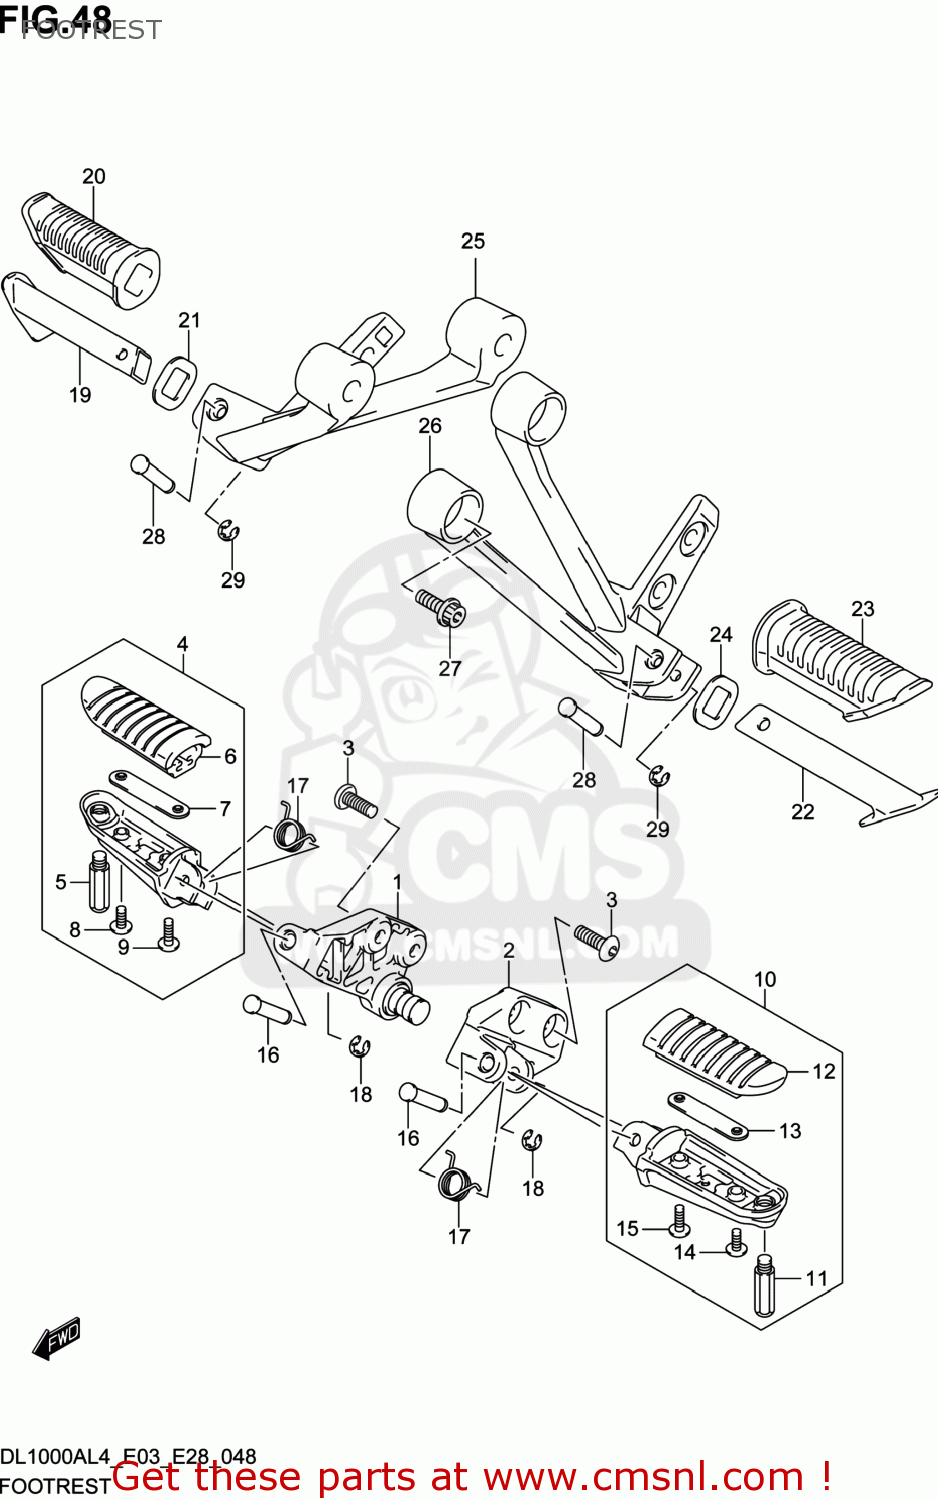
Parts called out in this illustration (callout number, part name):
1	BRACKET,FR FOOTREST,R
2	BRACKET,FR FOOTREST,L
3	BOLT(8X23)
4	FOOTREST ASSY,FRONT,R
5	SENSOR,FOOTREST
6	RUBBER,FOOTREST
7	PLATE,FR FOOTREST RUBBER
8	SCREW
9	SCREW
10	FOOTREST ASSY,FRONT,L
11	SENSOR,FOOTREST
12	RUBBER,FOOTREST
13	PLATE,FR FOOTREST RUBBER
14	SCREW
15	SCREW
16	PIN
17	SPRING
18	E RING
19	BAR,PILLION FOOTREST,R
20	RUBBER,PILLION FOOTREST
21	WASHER
22	BAR,PILLION FOOTREST,L
23	RUBBER,PILLION FOOTREST
24	WASHER,FOOTREST RUBBER
25	BRACKET,PILLION FOOTREST,R
26	BRACKET,PILLION FOOTREST,L
27	BOLT(8X30)
28	PIN
29	E RING
